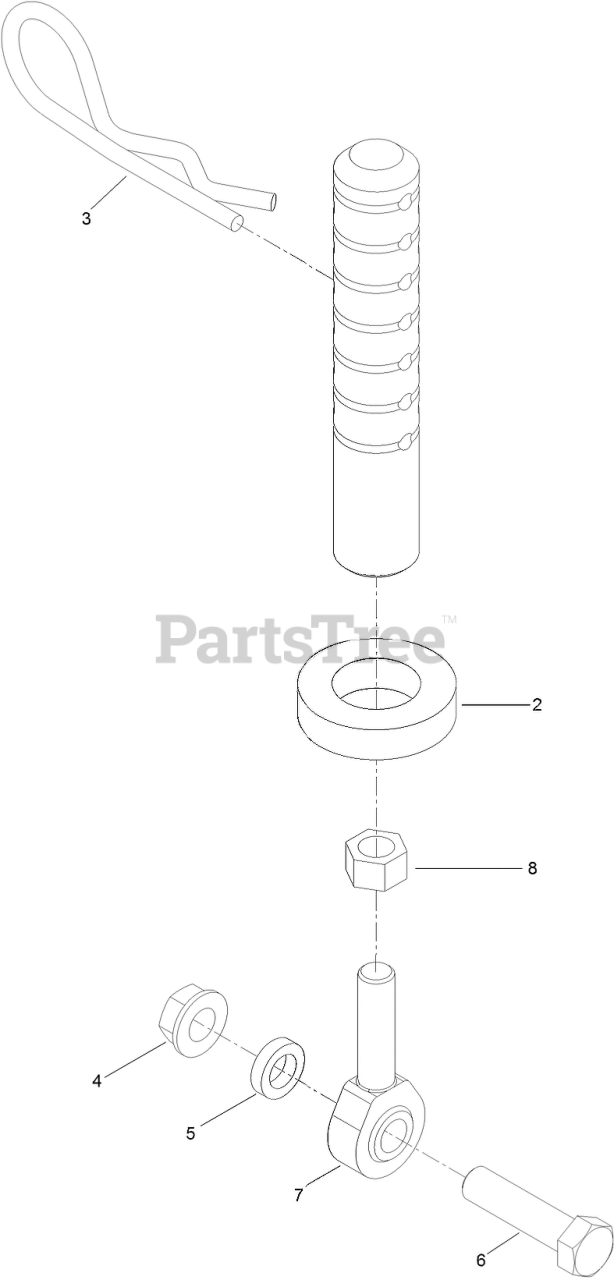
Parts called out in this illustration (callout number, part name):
2	SPACER-DECK SUPPORT
3	PIN-CUT HEIGHT
4	NUT-HHF, WHIZ
5	SPACER-IDLER
6	SCREW-HH
7	BALLJOINT
8	NUT-HJ
